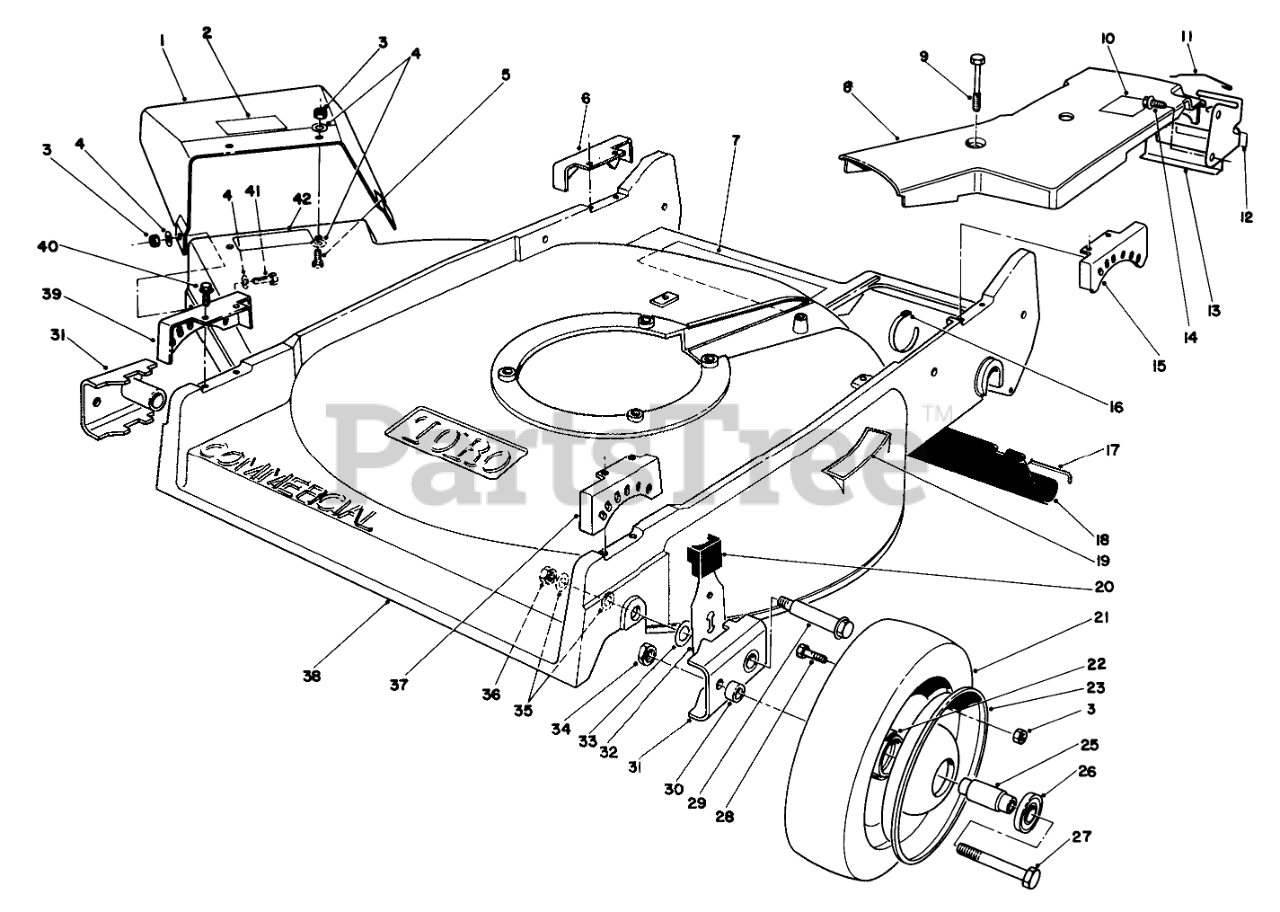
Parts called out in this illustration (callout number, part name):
1	Assembly-Deflector (Incl. Ref. #2)
2	Decal Danger
3	NUT-LOCK, NI
4	WASHER-FLAT
5	SCREW-HH
6	QUADRANT-REAR, RH
7	Decal-Safety Instructions
8	COVER-BELT
9	SCREW-HHFTF
10	Label-Grease
11	RETAINER-CABLE
12	DECAL-POSITION, GEAR
13	BRKT-TRACTION ADJ.
14	SCREW-HWHTF
15	QUADRANT-REAR, LH
16	TIE-CABLE
17	ROD-SHIELD
18	SHIELD-TRAILING
19	DECAL - STEP PAD INT'L
20	KNOB-ARM
22	HUB-BEARING
23	Wheel-Half
25	SPACER-BEARING
26	BEARING-WHEEL
27	SCREW-HH
28	SCREW-HH
29	WHEEL BOLT
30	SPACER-WHEEL
31	ARM-PIVOT, FRONT
32	FRONT SPRING ARM ASM
33	WASHER-THRUST
34	NUT-LOCK, CONE
35	WASHER
36	Nut
37	QUADRANT-FRONT, LH
38	Housing-Commercial (Incl. Ref. #7, 19 & 42)
39	QUADRANT-FRONT, RH
40	SCREW-HWHTF
41	SCREW-HH
42	DECAL - WARNING/INT'L
